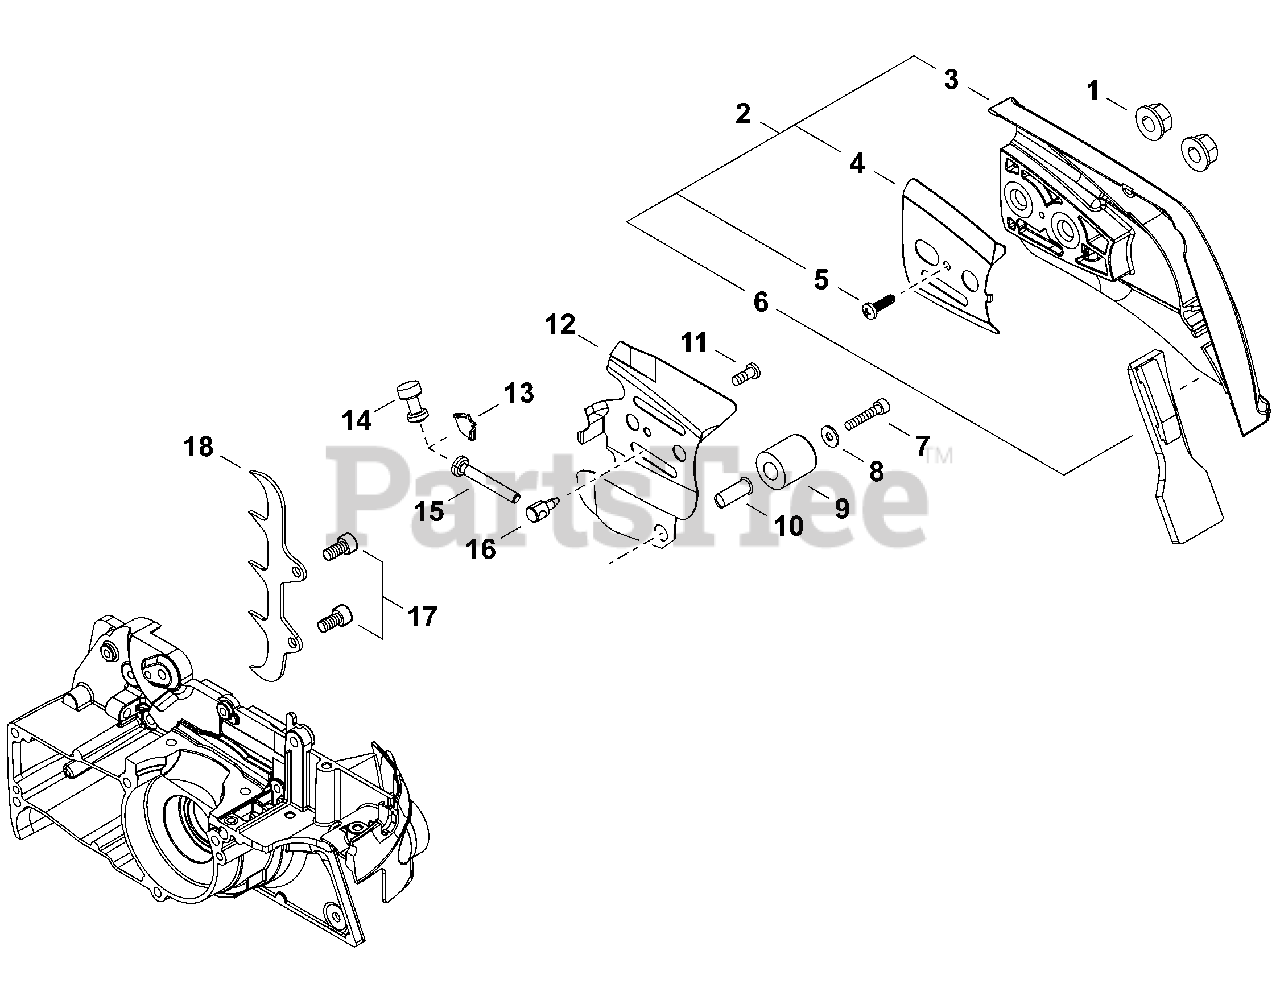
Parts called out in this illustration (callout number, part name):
1	NUT, FLANGE M8×1.25
2	COVER ASSY, CLUTCH
3	GUARD, SPROCKET
4	PLATE, GUIDE - OUTER
5	SCREW 4×8
6	PROTECTOR
7	BOLT 5×30
8	WASHER, FLAT 5.5×10×0.8
9	CHAIN CATCHER
10	COLLAR 5
11	SCREW M4×7
12	PLATE, GUIDE - INNER
13	GUIDE, GEAR
14	SCREW, ADJUSTER
15	SCREW, CHAIN TENSION
16	TENSIONER, CHAIN
17	BOLT 5×12
18	SPIKE, BUMPER
